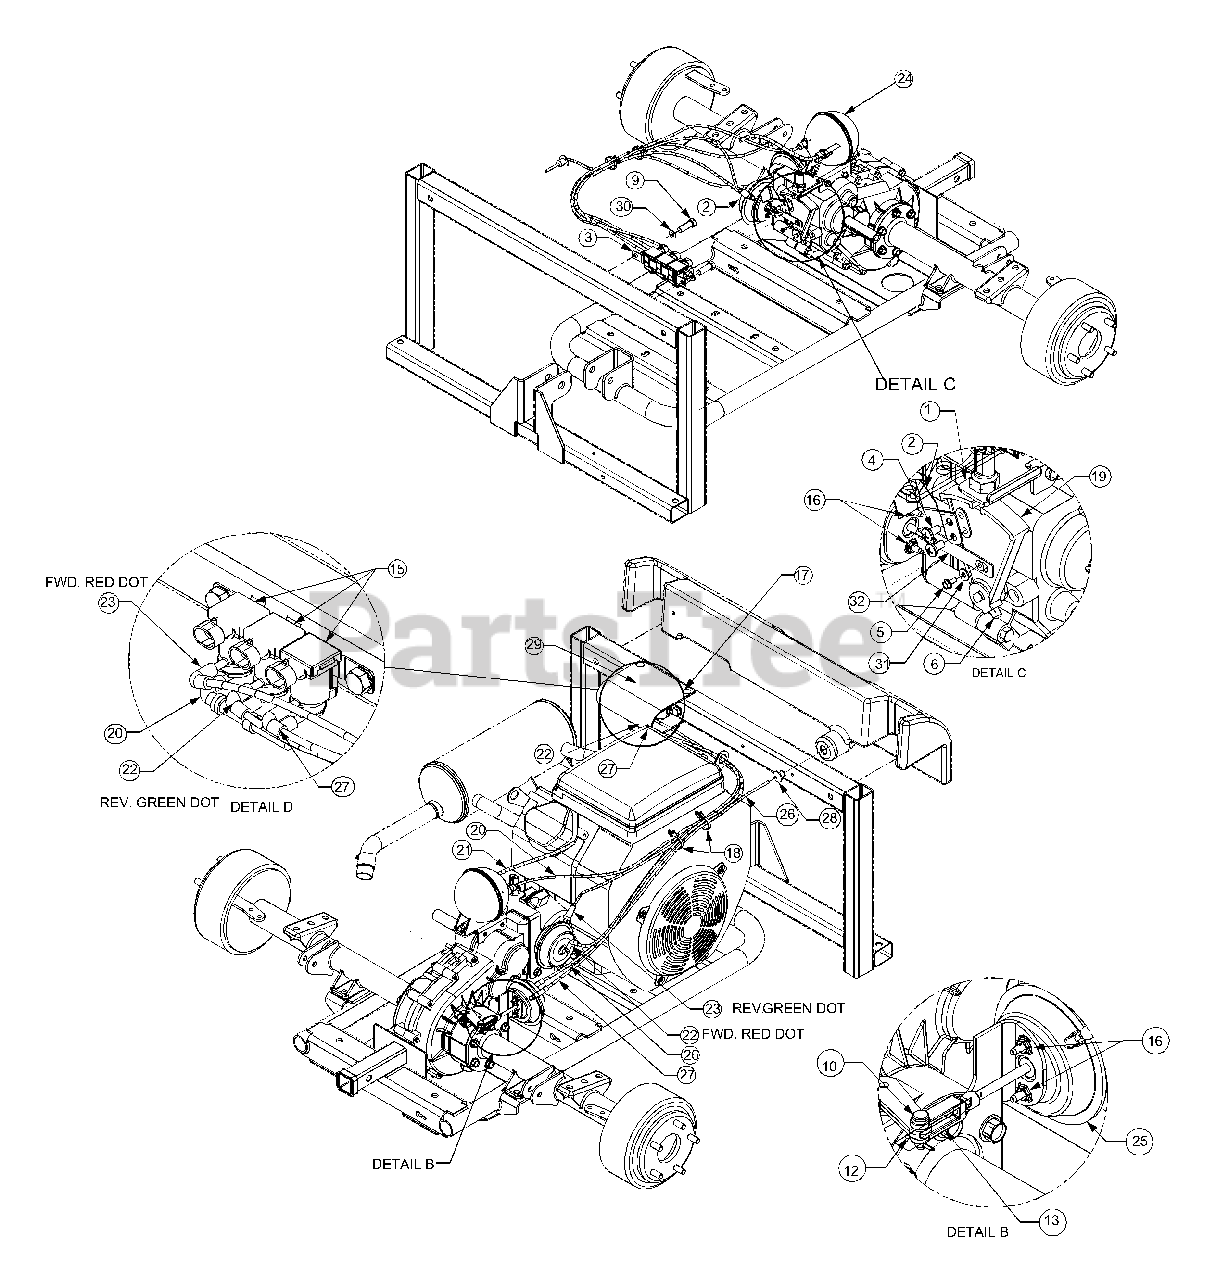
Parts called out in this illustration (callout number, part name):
1	Mounting Bracket, Vacuum Actuator
2	Bracket, Shift
3	Bracket, Vac Relay
4	Screw, 1/4-20 x.5
5	Screw, Hex. #8 - 18 .375
6	Screw, Set, 5/16-24 x .50 LG
9	Screw, 1/4-14 x .625 Hex
10	Pin, Clevis .312 OD x 1.0
12	Pin, Cotter 3/32x.750
13	Yoke, 1/4-28
15	Solenoid,Kit Vacuum Actuator
16	Self Threading Nut
17	Clip, Panel Retainer
18	Cable Tie
19	Arm, Shift
20	Hose
21	Hose, Manifold Vacuum
22	Hose, Actuator Vacuum
23	Hose, Actuator Vacuum
24	Reservoir, Air
25	Actuator, Vac Differential Lock
26	Hose, Vac Differential Lock, Vent
27	Hose, Vac Differential Lock Supply
28	Grommet, .58 x .25
29	Cover, Solenoid
30	Flat Washer, .330 x .687 x .030
31	Flat, Washer, .188 x .437 x .042
32	Actuator, Vacuum Shift
